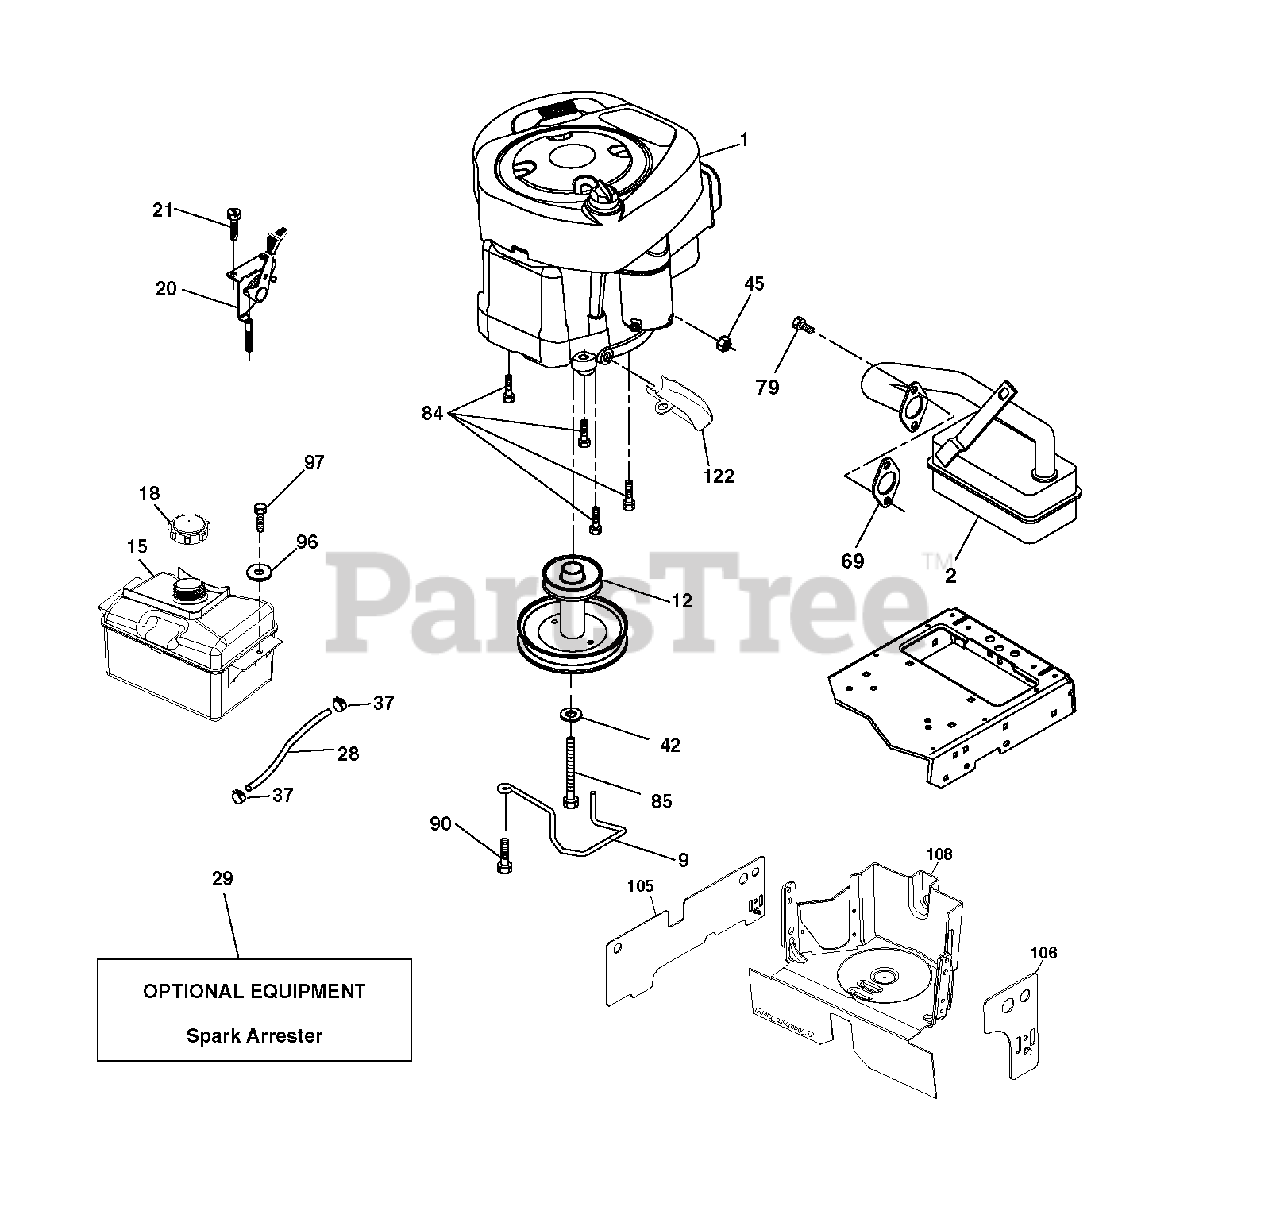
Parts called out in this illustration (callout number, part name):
9	KEEPER.BELT.ENGINE.3.25
12	PULLEY ENGINE
15	TANK FUEL FRT 1.5 GAL
18	CAP ASM.FUEL.2.25"FR.
20	CONTROL.TH/CK.C.
21	SCREW.#10 X 0.750.BOS THREAD
28	LINE.FUEL.20
29	ARRESTER SPARK (OPTIONAL)
37	HOSE CLAMP
42	LOCKWASHER
45	NUT
69	REPL BY 532 27 22-93
79	SCREW.SOCKET HD.5/16-1
84	SCREW.3/8-16
85	BOLT HEX 7/16-20X4-1/4"
90	SCREW 3/8-16X1
97	SCREW HEXWSHR 1/4-20X3/4
122	EXTENSION DRAIN OIL
